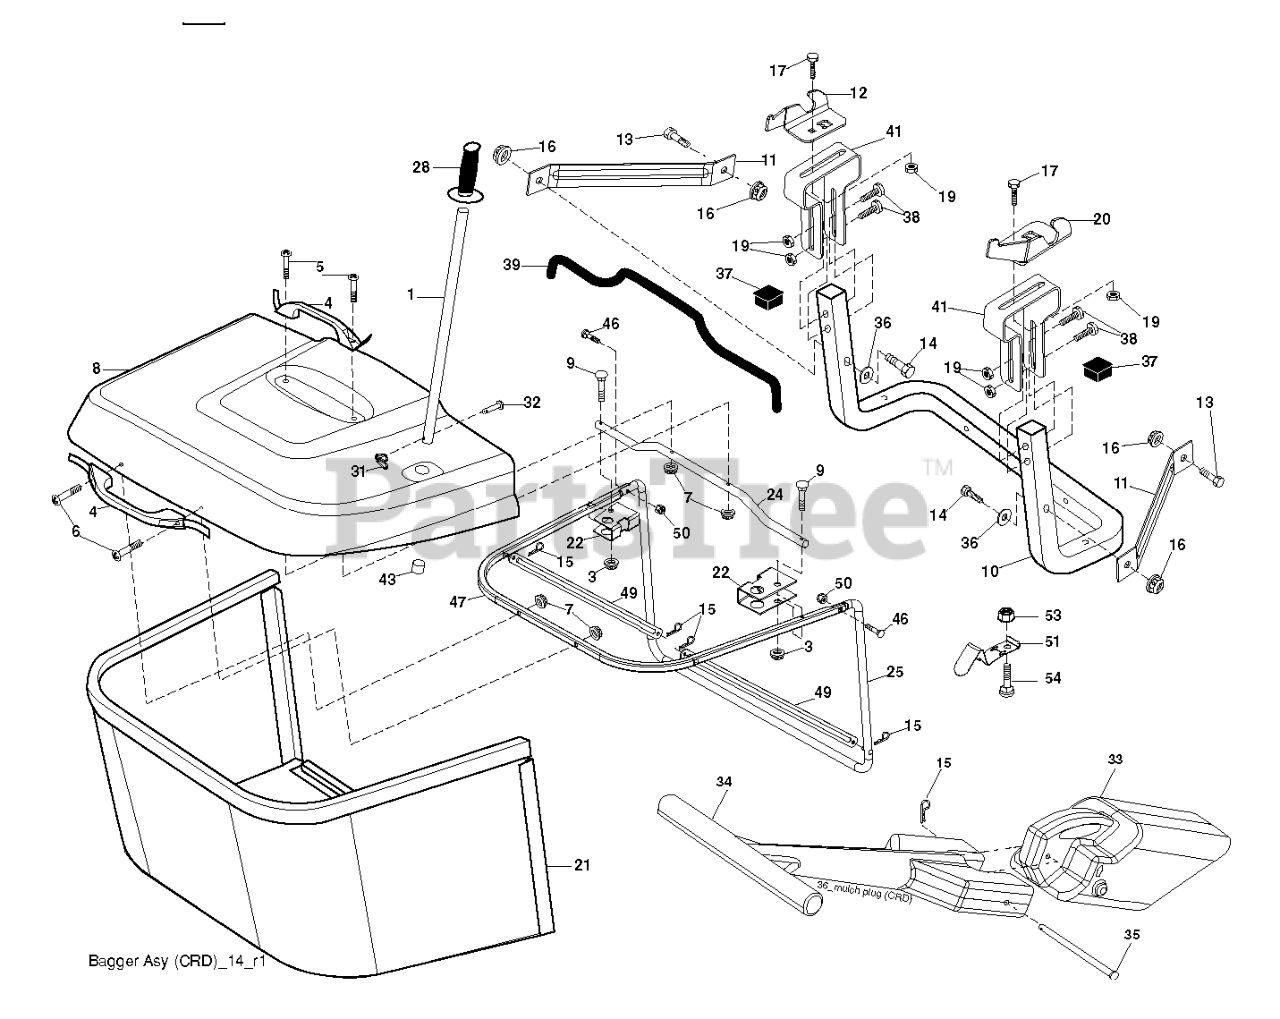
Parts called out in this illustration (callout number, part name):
1	TUBE.HANDLE.BAGGER.CRD/SRD.BLA
3	NUT T
4	HANDLE.BAGGER.W/LVRS.BLK.CRD
5	SCREW.PAN.HEAD
6	REPL BY 532 75 00-29
8	COVER.PNT.BGR.CRD.WSLOTS.MS668
9	Bolt Carriage 1/4-20 x 2.25d x Gr.5
10	TUBE
11	BRACKET.SUPPORT.UPPER.BAG.CRD
12	BRKT PIVOT
14	BOLT-HEX EAK
15	RETAINER-SPRNG RB
16	NUT LOCK FLG 3/8-16 UNC
17	RP BOLT 5/16-18 X3/4 ZN/YEL GR
19	NUT LOCK HEX FLANGE 5/16-18
20	BRKT.PIVOT.RH.CRD
21	BAGGER.ASM.CRD.2007
22	BRKT.SIDE.BAG.CRD
24	TUBE.PIVOT.BAG.CRD.BLACK
25	PIPE
28	GRIP.HANDLE.BLACK
31	RETAINER CLIP
32	RIVET,DRILLED
33	MULCHING.PLUG.107.CRD.(2 2)
34	HANDLE.MULCHER.92.CRD (2 2)
36	WASHER
37	Plug Support Bagger CRD
38	BOLT.5/16-18X2.5
39	SEAL.BAGGER.CRD
41	BRKT.VERT.ADJ.BAGGER.CRD
43	PLUG, TUBING END
46	BOLT.CARRIAGE.5/16-18
47	PIPE
49	ROD
50	NUT.71038.31-18.HEX.NYLOCK
51	LATCH
53	NUT
54	BOLT
